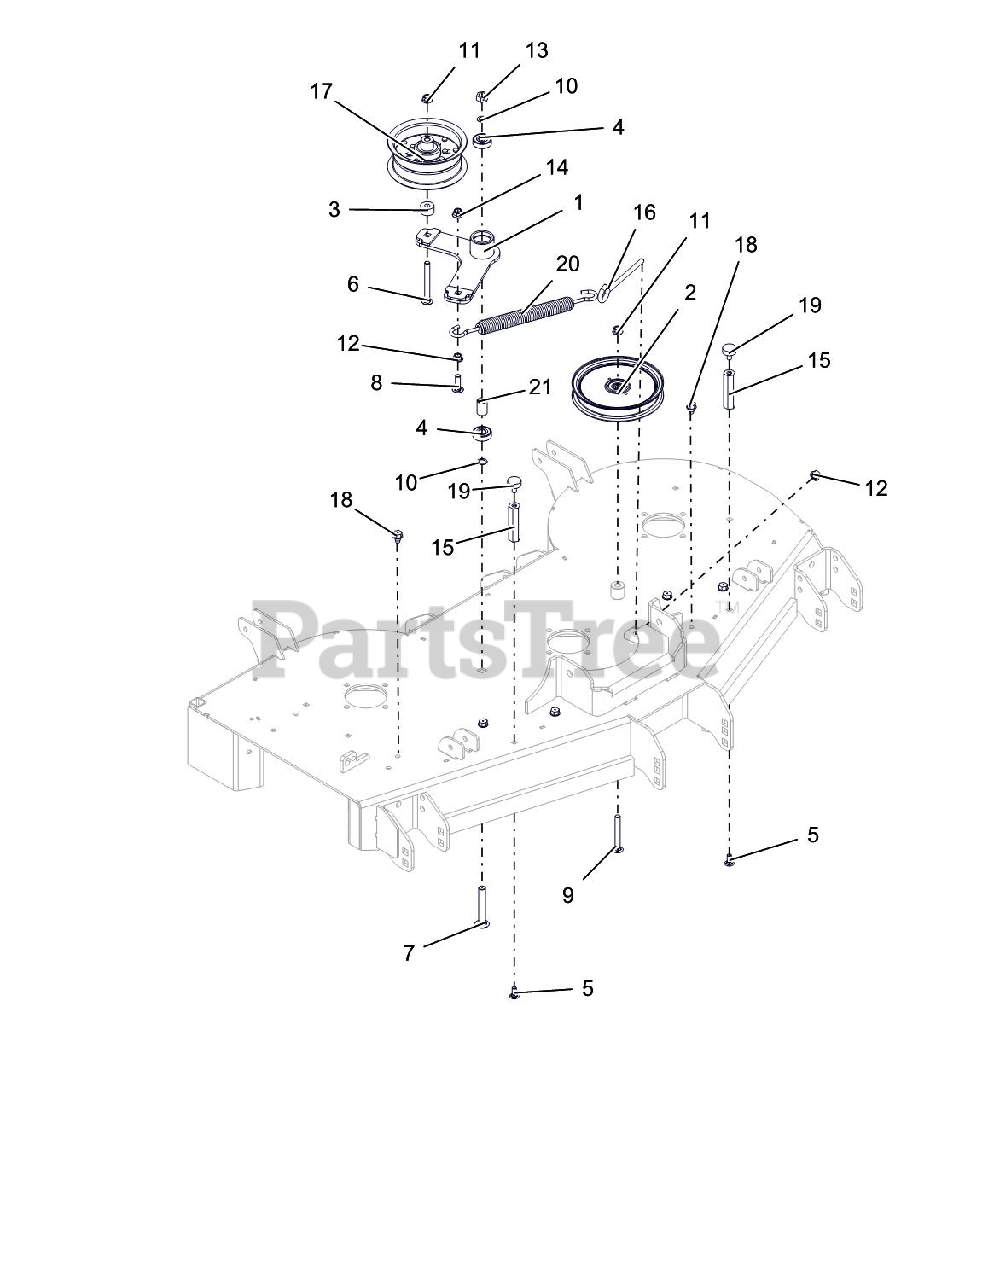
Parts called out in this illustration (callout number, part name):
1	WLDMT, DECK IDLER ARM
2	IDLER, FLAT-6.00" X .75"
3	SPACER .390X1.000X.562
4	BRG-BALL .500X1.38X.437
5	BLT,RDHDSQNK .31-18X.75 LOCTIT
6	@BLT-RHDSSQNK .38-16X3.50 G5YZ
7	BLT,RDHDSQSHNK.50-13X3.25 G5YZ
8	@BLT-RHDSSQNK .38-16X1.25 G5YZ
9	@BLT-RDHDSQNK .38-16X3.00 G5YZ
10	WASHER, .500X.750X.020 THRUST
11	NUT-LK-CTR-FLG .38-16 YWZC
12	@NUT-SPNLK-FLG .375-16 YWZC
13	@NUT-LK-CTR .50-13 YWZC
14	@NUT-LK-NYL-FLG .38-16 YWZC
15	NUT, COUPLING .31-18 X 3.00
16	BOLT,.38-16 X 4.25-.62 DIA EYE
17	PULLEY, FLAT 5.00X2.36X.375
18	@SCR-TAP .38-16X.50 HWH TR YWZ
19	BUMPER, RUBBER
20	SPRING, EXTENSION
21	SPACER .510 X .75 X 1.1485
